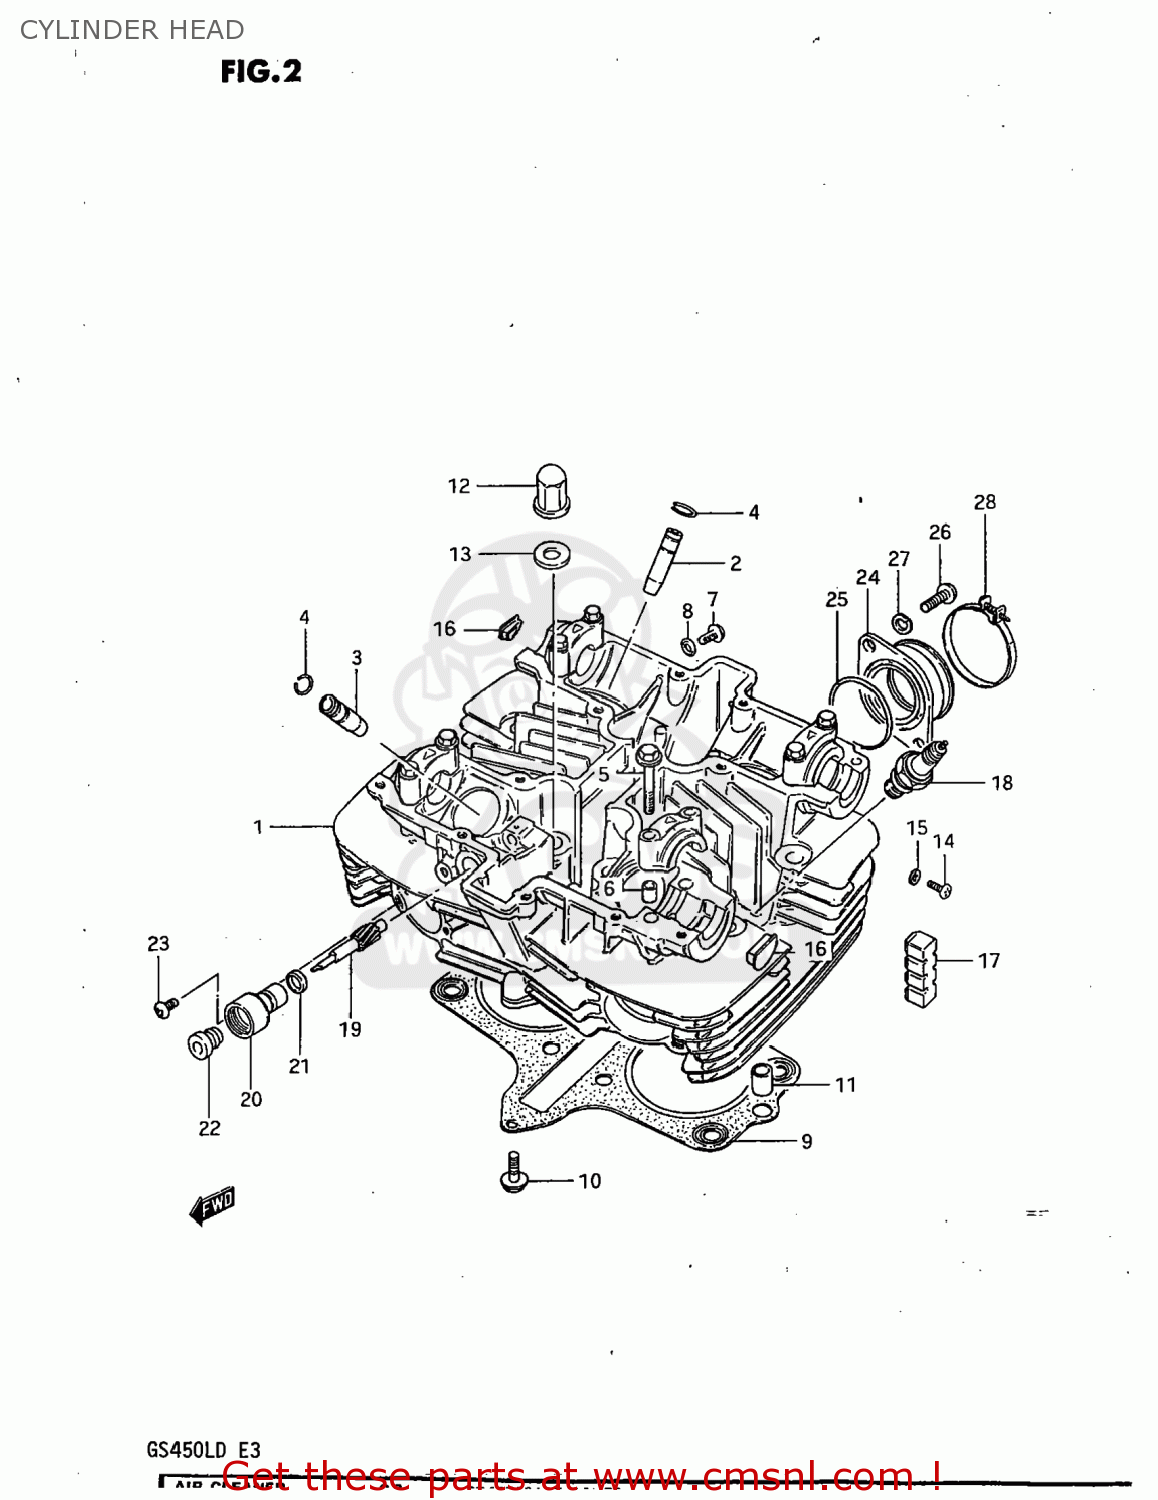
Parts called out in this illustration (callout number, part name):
1	HEAD SET,CYLINDER
2	GUIDE,INTAKE VALVE
3	GUIDE,EXHAUST VALVE
4	RING,SNAP
5	BOLT(6X39)
6	PIN(6.2X8X11)
7	BOLT
8	GASKET (NAS)
9	GASKET,CYLINDER HEAD (MCA)
10	BOLT
11	PIN
12	NUT
13	GASKET(10.5X22X2) (NAS)
14	SCREW
15	GASKET(5.3X9.3X1.2) (NAS)
16	PLUG
17	PAD,CYLINDER
18	SPARK PLUG
19	GEAR,TACHOMETER DRIVEN
20	SLEEVE,TACHOMETER DRIVE GEAR
21	SEAL,TACHOMETER DRIVEN
22	SEAL,OIL(5X12X8)
23	SCREW(5X12)
24	PIPE,INTAKE
25	O-RING (D:2.4 ID:39.7)
26	SCREW
27	LOCK WASHER
28	CLAMP
